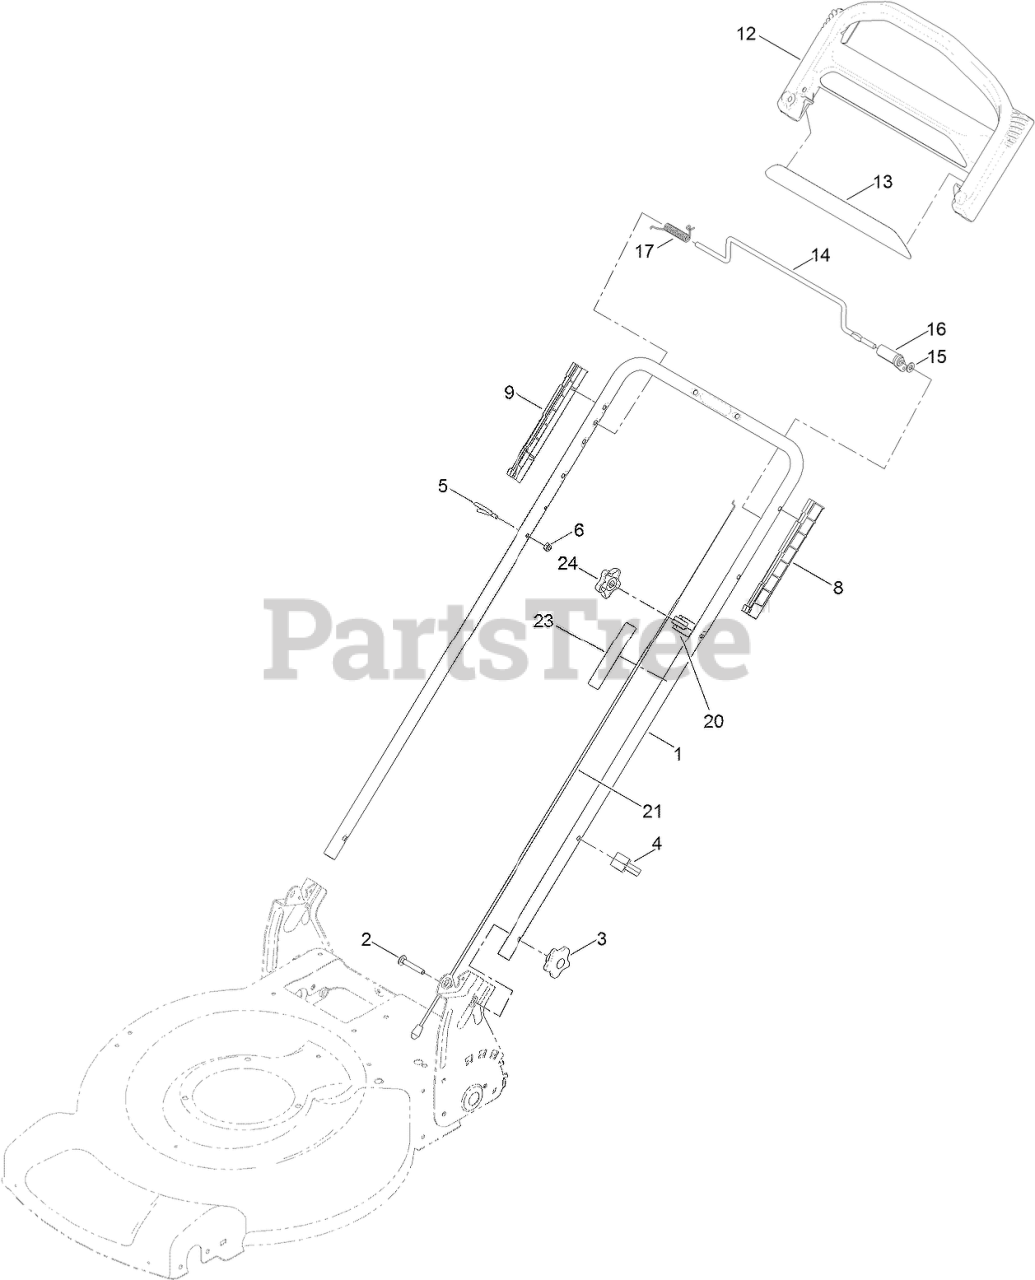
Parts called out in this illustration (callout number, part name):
2	Screw-CARR
3	KNOB-HANDLE
4	GUIDE-CABLE
5	GUIDE-ROPE
6	NUT-LOCK, NI
8	GUIDE-LH
9	GUIDE-RH
12	HANDLE-CONTROL
13	DECAL-HANDLE
14	BAR-CONTROL, TRACTION
15	WASHER-PLAIN
16	LEVER-TRACTION
17	Spring-Torsion
20	ANCHOR-CABLE
21	CABLE-TRACTION
23	DECAL-TRACTION, ADJUST
24	KNOB-HANDLE, LOCKING
